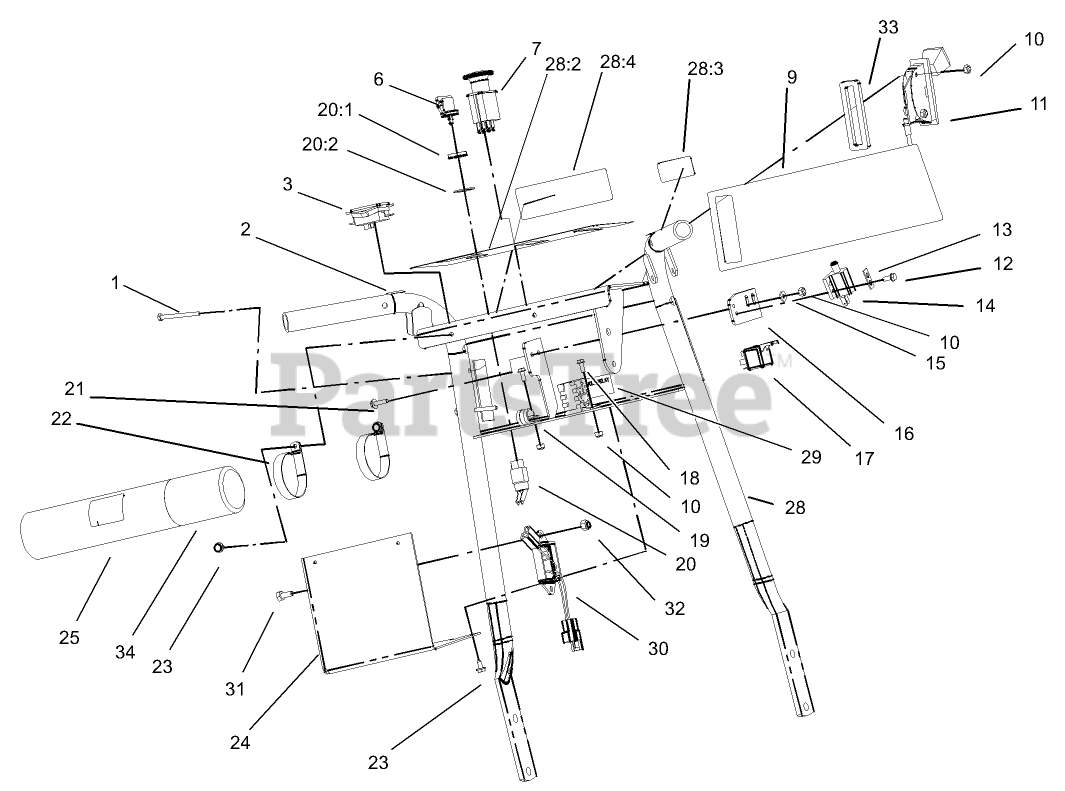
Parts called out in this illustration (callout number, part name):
1	SCREW-SHH
2	DECAL-LOCK, NEUTRAL
3	HOURMETER
6	KEY-IGNITION
7	SWITCH-PTO
9	DECAL-CONTROL, THROTTLE
10	NUT-LOCK, NI
11	CONTROL-THROTTLE
12	SCREW-TAPTITE
13	PLATE-SWITCH
14	SWITCH-POLE, SINGLE
15	WASHER-FLAT
16	PLATE-MOUNTING, SWITCH
18	SCREW-HWH
19	CLAMP-R
20	SWITCH-ON / OFF
20:1	NUT-HH
20:2	WASHER-TOOTH, INTERNAL
21	SCREW-HWH
22	CLAMP-R
23	SCREW-HWHTF
24	BRACKET-COVER
25	TUBE-MANUAL
28	HANDLE ASM
28:2	DECAL-PANEL, CONTROL
28:3	DECAL-PROTECTION, EAR
28:4	DECAL-WARNING
29	DECAL-RELAY, 24 VOLT
30	Module-Filter
31	SCREW-HH
32	NUT-LOCK, NI
34	CAP-HOUSING
